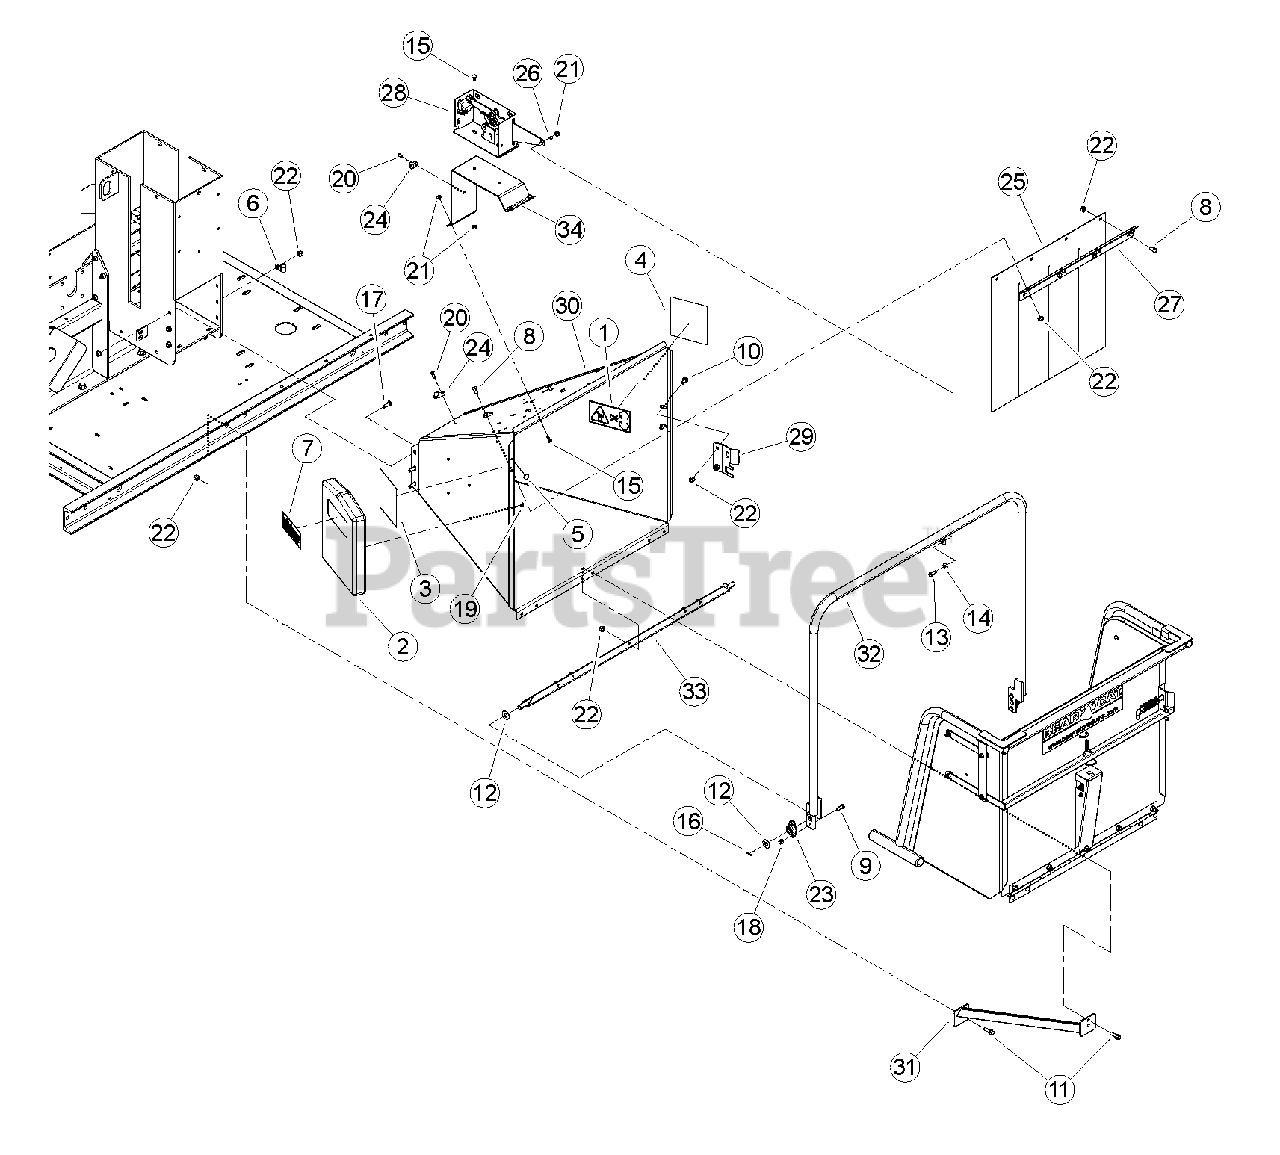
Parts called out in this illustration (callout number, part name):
1	DECAL, BLADE DANGER ISO
2	CONTAINER, INSTR. MANUAL
3	DECAL, FEED POSITION
4	DECAL, FEED POSITION
5	BUMPER, RUBBER
6	CLAMP, 9/16 COATED
7	DECAL, MUTILINGUAL MANUAL
8	BOLT, 3/8 X 3/4 GR5 HEX CAPSCREW ZP
9	BOLT, 3/8 X 1 HEX HD GR5 ZP
10	BOLT, 3/8 X 1" GR5 CRG NC ZP
11	BOLT, 3/8 X 1-1/4 FLANGE NC
12	WASHER, 5/8" SAE FLAT ZP
13	BOLT, 5/16 X 1" GR5 HHCS NC ZP
14	WASHER, 5/16" FLAT ZP
15	BOLT, 5/16 X 3/4 GR5 CRG NC ZP
16	PIN, 1/8 X 1.00 ZP COTTER
17	BOLT, 3/8 X 1-1/4" GR5 CRG NC ZP
18	NUT, 3/8" NE NYLOCK ZP
19	RIVET, AL BLIND 1/4 X 1/2 DOME HEAD
20	RIVET, AL BLIND 1/4 X 3/4 DOME HEAD
21	NUT, 5/16-18 NYLOCK-FLANGE
22	NUT, 3/8-16 NYLOCK FLANGE
23	BEARING, SIDE FLANGE MOUNT 5/8"
24	CLAMP, CABLE MOUNT
25	FLAP, 9 INCH CHUTE
26	SPACER, IDLER PIVOT
27	SUPPORT, 9 INCH CHIPPER FLAP
28	ASSEMBLY, "CE" SWITCH BOX
29	PLATE, TRAY STOP
30	WELDMENT, BIG CHIPPER CHUTE
31	WELDMENT, CHUTE SUPPORT
32	WELDMENT, CONTROL ARM
33	WELDMENT, CONTROL PIVOT
34	MOUNT, SWITCH BOX
